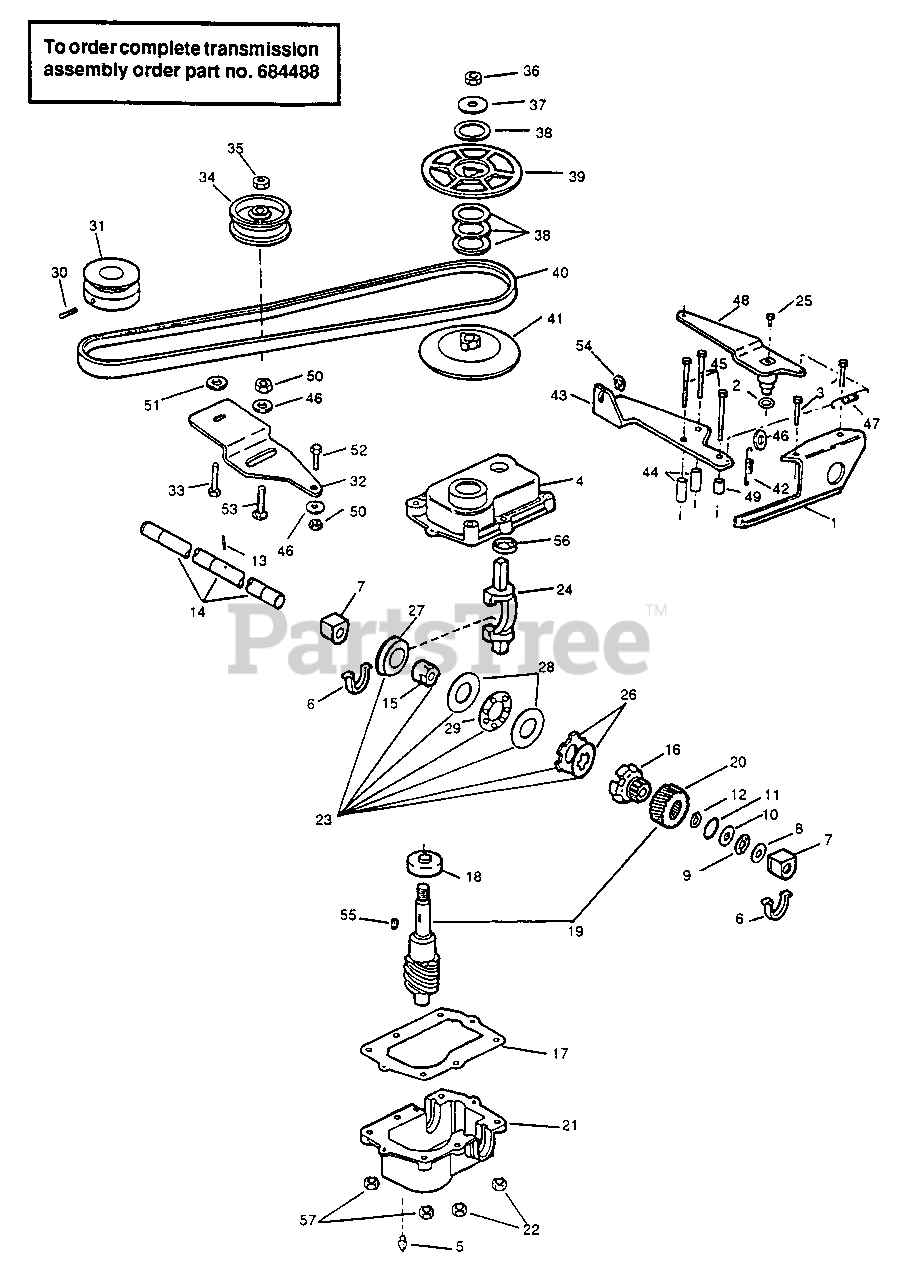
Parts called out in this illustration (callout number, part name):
1	Tensioner Bracket
2	O-Ring
3	Hex Hd. Cap Screw
4	Gearcase-Upper
5	Plug
6	Packing
7	Bearing & Seal-Gearcase
8	Thrust Washer
9	Thrust Bearing
10	Thrust Washer
11	Thrust Washer
12	Retaining Ring
13	Pin
14	Driveshaft
15	Driven Sleeve
16	Driver
17	Gasket
18	Bearing
19	Worm Wheel & Shaft (Inc. 20)
20	Worm Wheel
21	Gearcase-Lower
22	Nut, Lock
23	Collar, Brg & Disc Kit (Inc. 24-29)
24	Shift Fork
25	Screw
26	Disc Plate Kit
27	Collar
28	Thrust Washer
29	Bearing
30	Set Screw
31	Pulley-Engine
32	Bracket & Idler Assy (Inc. 33-35)
33	Screw
34	Pulley-Idler
35	Nut
36	Nut
37	Washer
38	Washer
39	Pulley-Upper Half
40	V-Belt
41	Pulley-Lower Half
42	Extension Spring
43	Conduit Anchor Bracket
44	Spacer
45	Screw
46	Washer
47	Extension Spring
48	Shift Arm & Hub Assembly
49	Spacer
50	Nut
51	Washer
52	Screw
53	Square Neck Bolt
54	Retaining Ring
55	Key
56	Seal Guide
57	Nut-Lock
